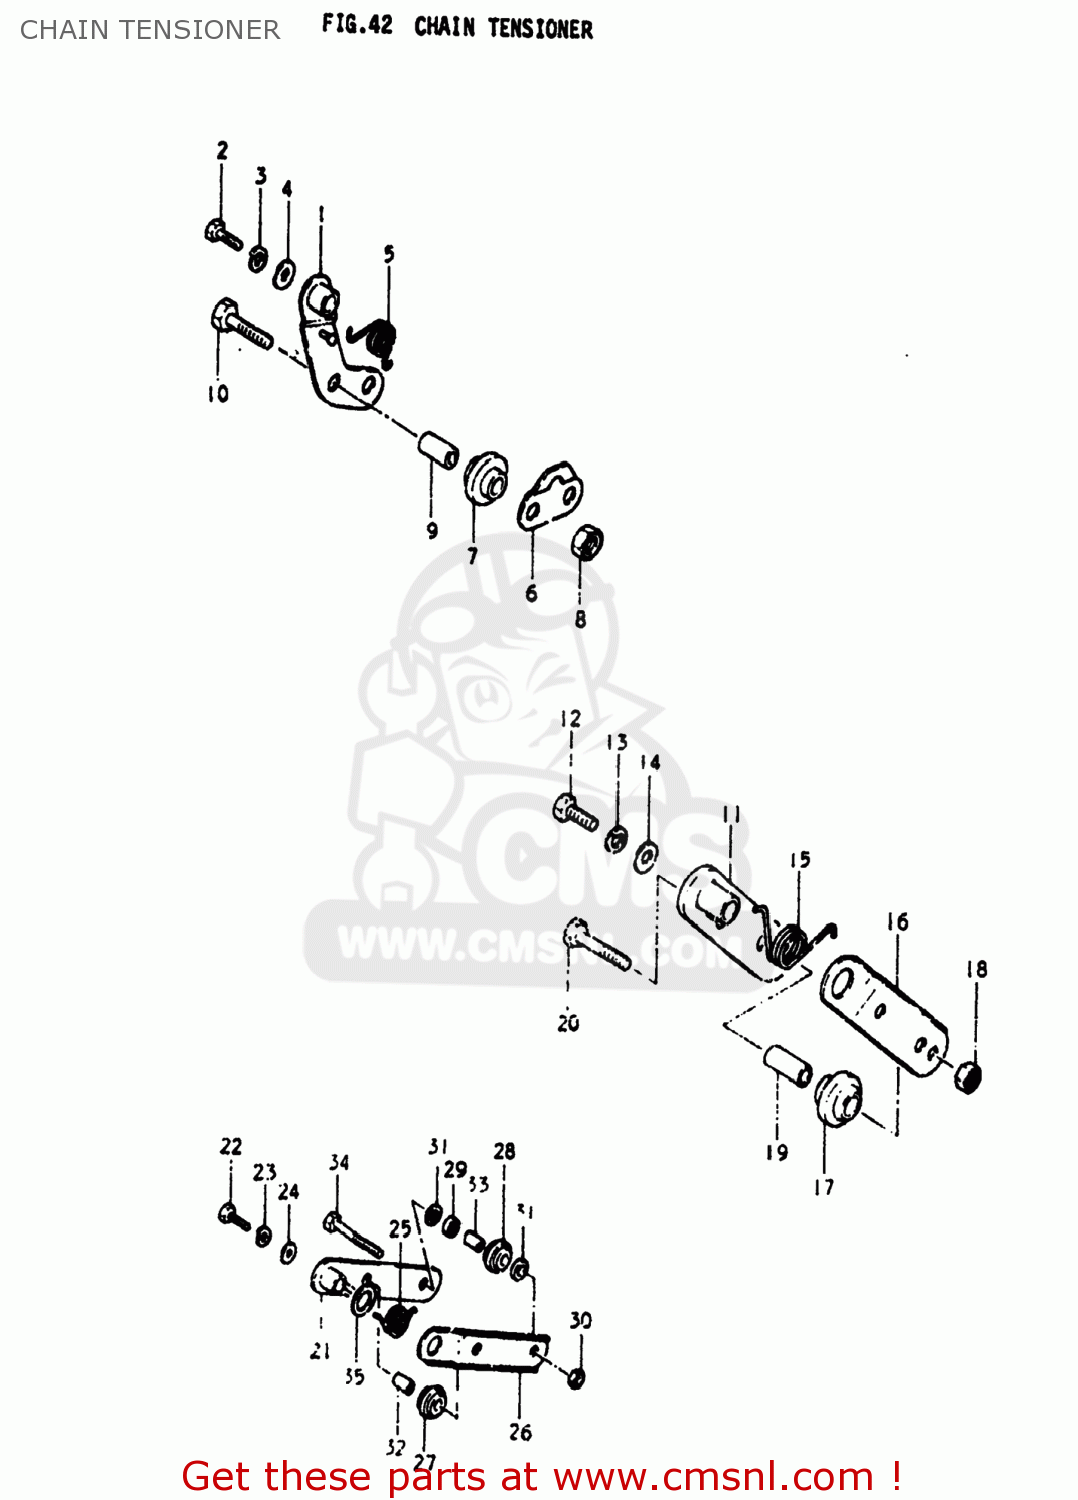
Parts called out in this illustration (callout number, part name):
1	TENSIONER,CHAIN
2	BOLT
3	LOCK WASHER
4	WASHER
5	SPRING
6	PLATE,CHAIN TENSIONER
7	RUBBER,CHAIN GUARD
8	NUT 6MM
9	SPACER(6.5X10.5X22.5)
10	BOLT
11	TENSIONER,CHAIN
12	BOLT
13	LOCK WASHER
14	WASHER
15	SPRING
16	PLATE,CHAIN TENSIONER
17	RUBBER,CHAIN GUARD
18	NUT 6MM
19	SPACER(6.5X10.5X22.5)
20	BOLT
21	TENSIONER,CHAIN
22	BOLT
23	LOCK WASHER
24	WASHER
25	SPRING
26	PLATE,CHAIN TENSIONER OUTER
27	RUBBER,CHAIN GUARD
28	ROLLER,CHAIN TENSIONER LWR
29	BEARING(10X14X15)
30	NUT 6MM
31	SEAL,OIL(10X14.4X3.5)
32	SPACER(6.5X10.5X22.5)
33	SPACER(6.2X10X22.5)
34	BOLT
35	WASHER
